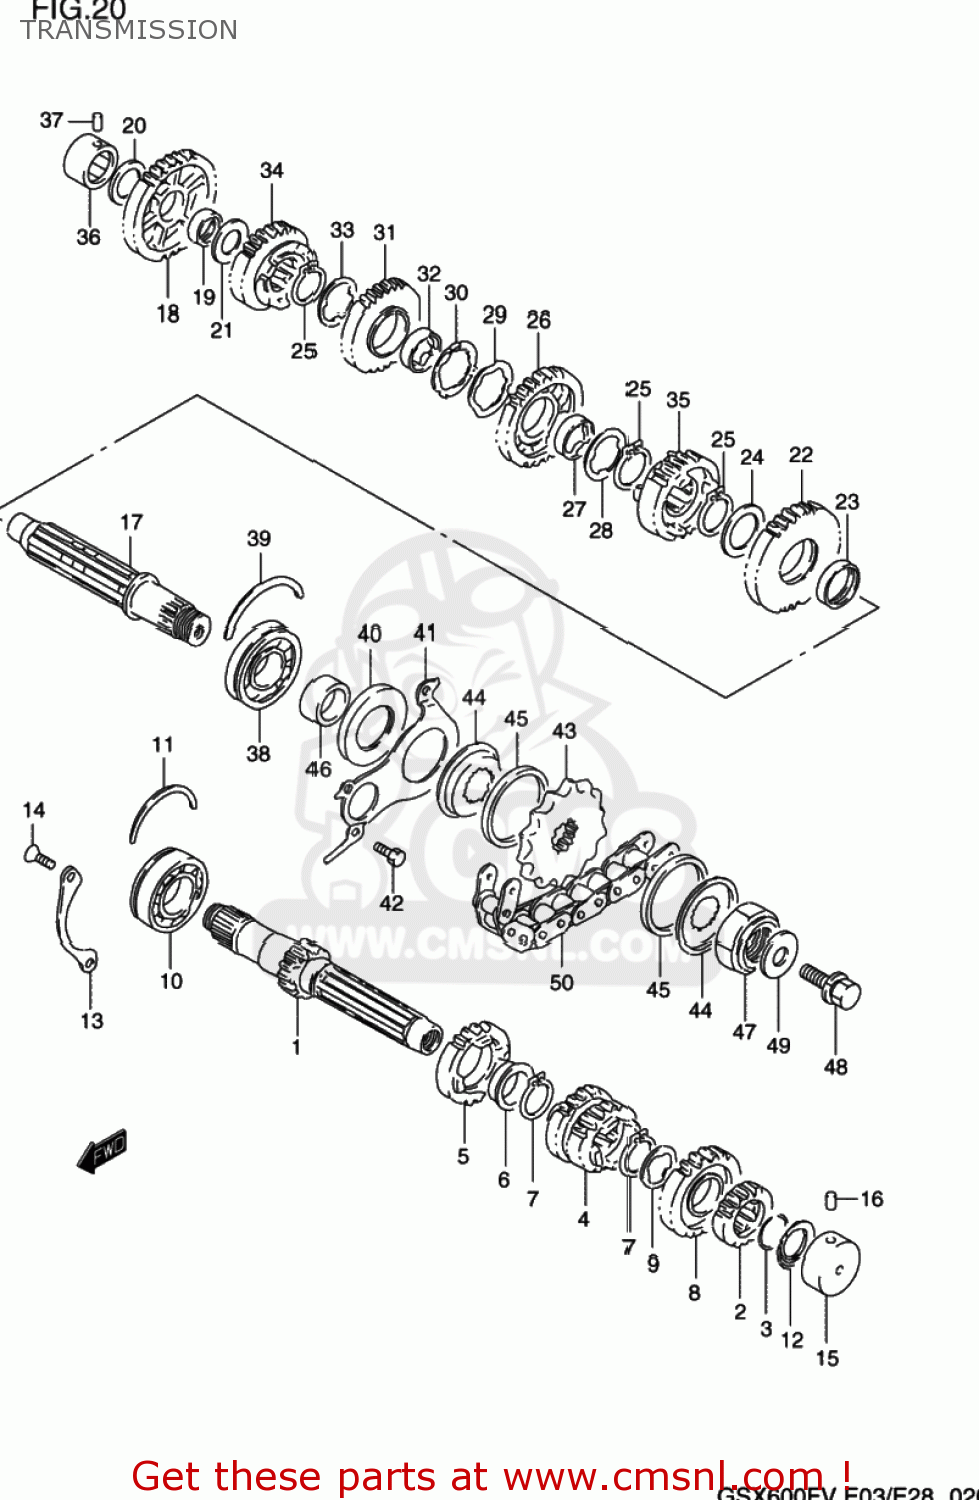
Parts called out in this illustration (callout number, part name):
1	SHAFT,COUNTER(NT:12)
2	GEAR,2ND DRIVE(NT:16)
3	CIRCLIP
4	GEAR,3RD & 4TH DRIVE(NT:17/20)
5	GEAR,5TH DRIVE(NT:22)
6	BUSHING
7	RING,SNAP
8	GEAR,SIXTH DRIVE (NT:21)
9	WASHER,LOCK
10	BEARING(25X62X17)
11	C RING
12	SEAL,OIL(20X31.2X2.7)
13	RETAINER,CNTR SHAFT BEARING
14	SCREW ,6X16
15	BEARING(20X34X17.5)
16	PIN
17	SHAFT,DRIVE
18	GEAR,1ST DRIVEN(NT:37)
19	BUSH(22X26X9)
20	SHIM(20X34X1)
21	SHIM(22X34X1)
22	GEAR,2ND DRIVEN(NT:33)
23	BUSH(28X32X9.5)
24	SHIM(28X38X1)
25	CIRCLIP
26	GEAR,3RD DRIVEN(NT:28)
27	BUSH
28	WASHER,LOCK
29	WASHER,LOCK
30	WASHER
31	GEAR,4TH DRIVEN(NT:28)
32	BUSH
33	WASHER,LOCK
34	GEAR,5TH DRIVEN(NT:27)
35	GEAR,SIXTH DRIVEN (NT:23)
36	BEARING(20X34X20)
37	PIN
38	BEARING(25X62X17)
39	C RING
40	SEAL,OIL(34X62X6)
41	RETAINER,DRIVE SHAFT OIL SEAL
42	BOLT
43	SPROCKET,ENGINE
44	HOLDER,SPROCKET DAMPER
45	DAMPER,SPROCKET
46	SPACER(25X34X16.1)
47	NUT
48	BOLT
49	WASHER
50	CHAIN,DRIVE(112LE)
